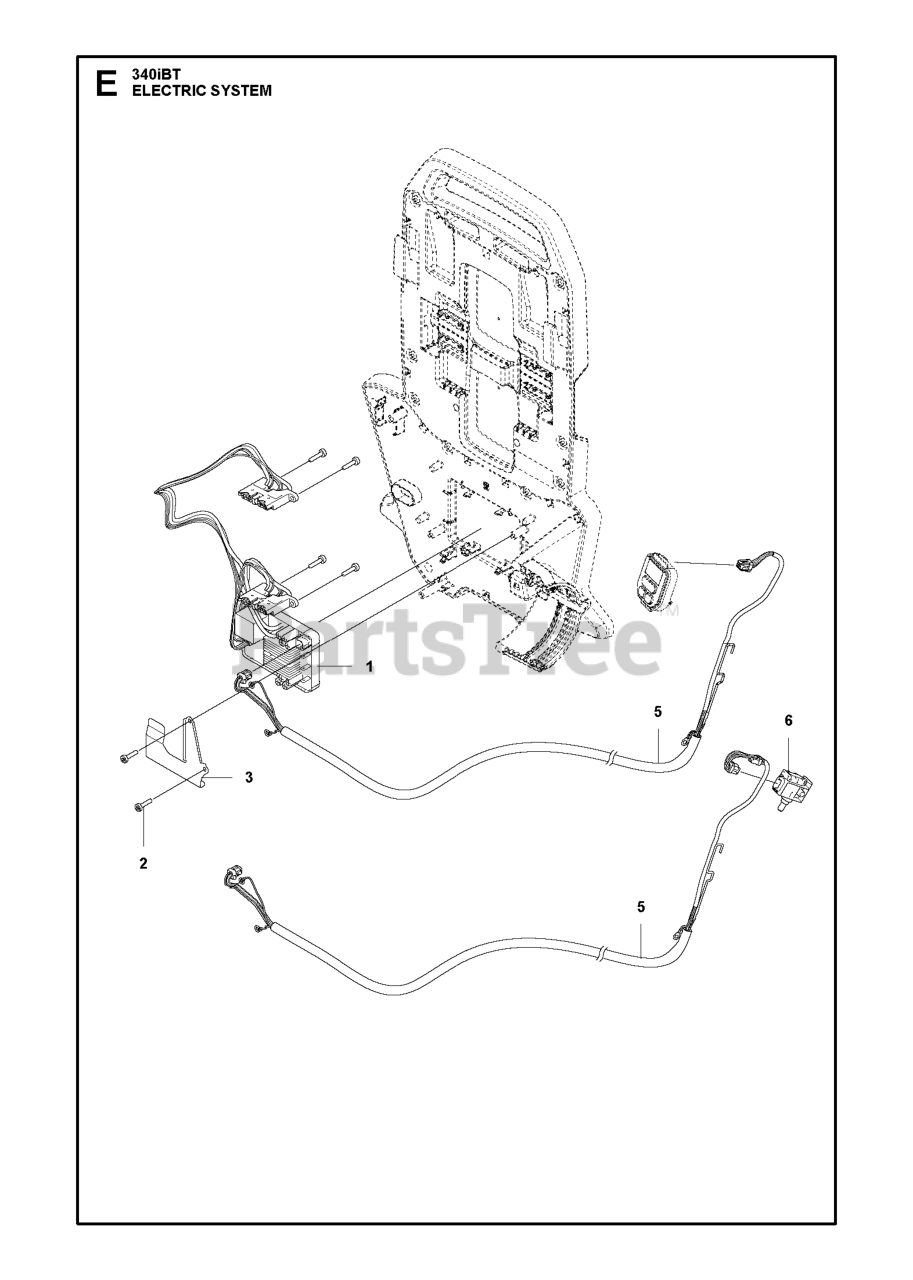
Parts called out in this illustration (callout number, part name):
1	Controls
2	SCREW ITXSCT PW4.2X18 10.9 ZN
3	SPRING PLATE ESD CONTROL UNIT
5	Wires
6	TRIGGER SWITCH IPX4
